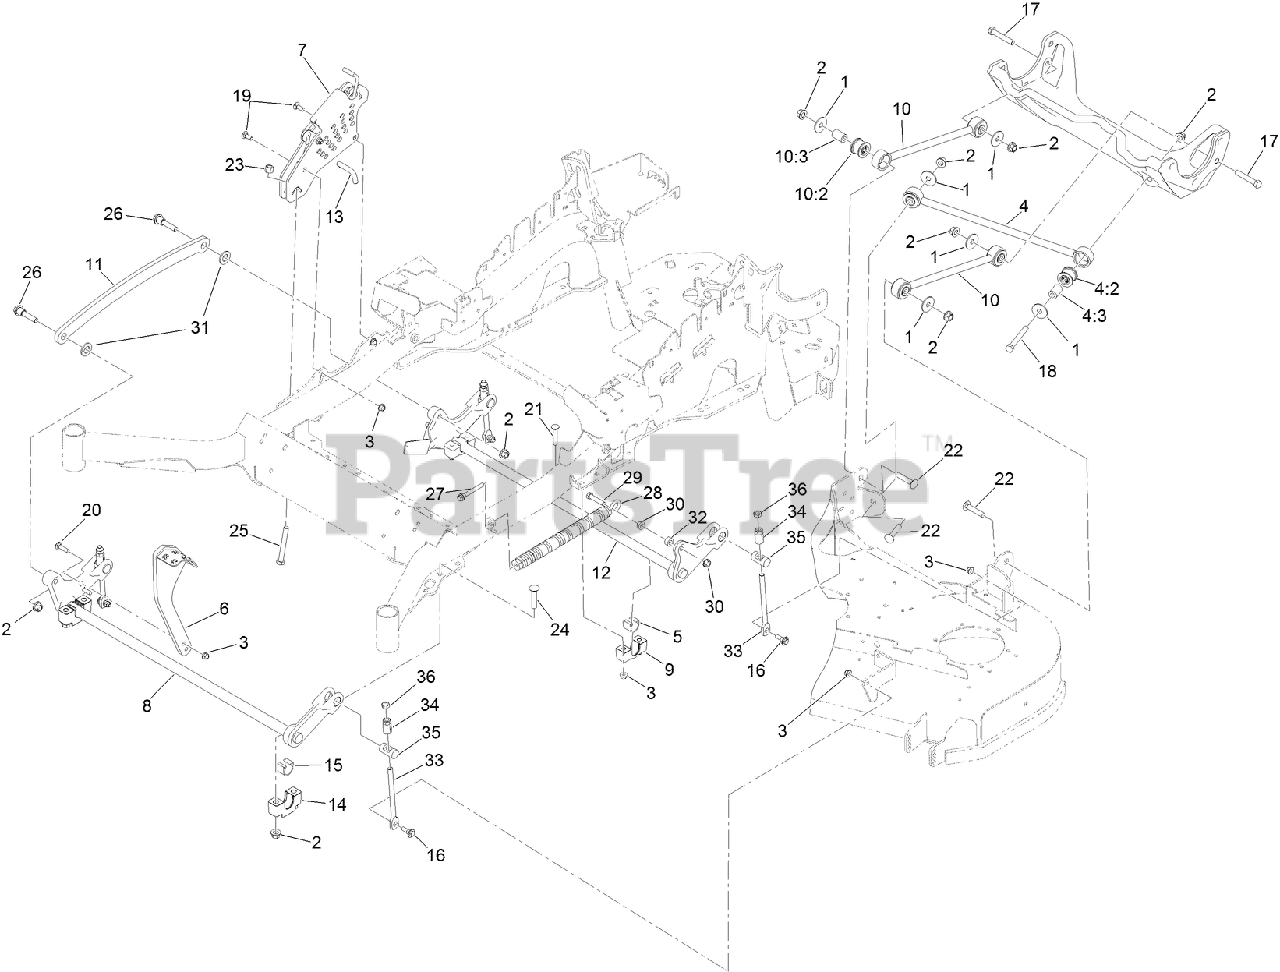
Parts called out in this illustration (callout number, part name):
1	WASHER-THRUST
2	NUT-LOCK
3	NUT-HF, NI
4	PANHARD ROD ASM
4:2	BUSHING-SUSPENSION, RUBBER
4:3	SPACER
5	BEARING-CROSS SHAFT, REAR
6	LEVER-FOOT
7	HEIGHT-OF-CUT ASM
8	DECKLIFT-FRONT
9	SUPPORT-CROSS SHAFT, BEARING REAR
10	DECK STRUT ASM
10:2	BUSHING-SUSPENSION, RUBBER
10:3	SPACER
11	LINK-LIFT, DECK
12	LIFT-DECK, REAR
13	PIN-HOC
14	SUPPORT-CROSS SHAFT, BEARING
15	BEARING-CROSS SHAFT, FRONT
16	SCREW-SHOULDER, HHF
17	SCREW-HH
18	SCREW-HH
19	SCREW-HH
20	SCREW-HH
21	SCREW-HH
22	SCREW-CARR
23	NUT-LOCK, NI
24	BOLT-CARR
25	BOLT-TAP
26	SCREW-HHF, SHOULDER
27	BOLT-SHOULDER
28	SPRING-EXTENSION
29	SCREW-HH
30	NUT-HF
31	WASHER-FLAT
32	SPACER
33	LINK-ADJUSTER, DECK LIFT
34	ADJUSTER-LIFT, DECK
35	TRUNNION
36	NUT-JAM
